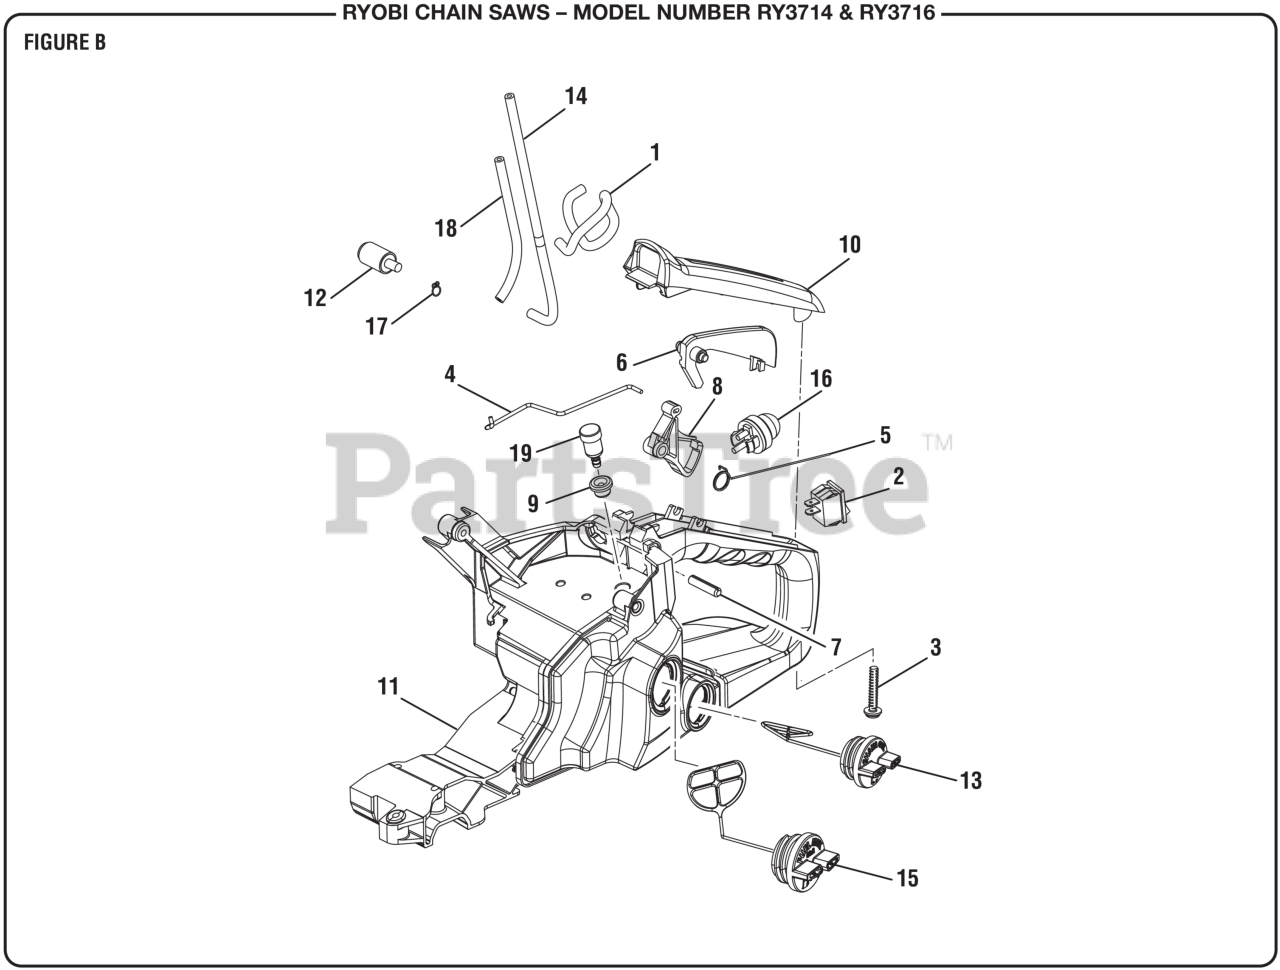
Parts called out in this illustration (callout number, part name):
1	Fuel Hose (Primer Assembly to Carburetor, 160 mm)
3	Screw (M5 x 27 mm, T25 Torx Pan Hd.)
4	Throttle Rod.
5	Throttle Spring
6	Safety Rock Arm
7	Spring Pin
8	Throttle Trigger
10	Grip Cover
11	Rear Handle Assembly
12	Fuel Filter Assembly
13	Oil Cap Assembly
14	LP-1500 Tubing (205.00 mm)
15	Fuel Cap Assembly
16	Primer Bulb Assembly
17	CLIP-HOSE (ID 4.9)
18	Fuel Hose (Primer Assembly to Tank, 153 mm)
19	Fuel Breather Assembly
